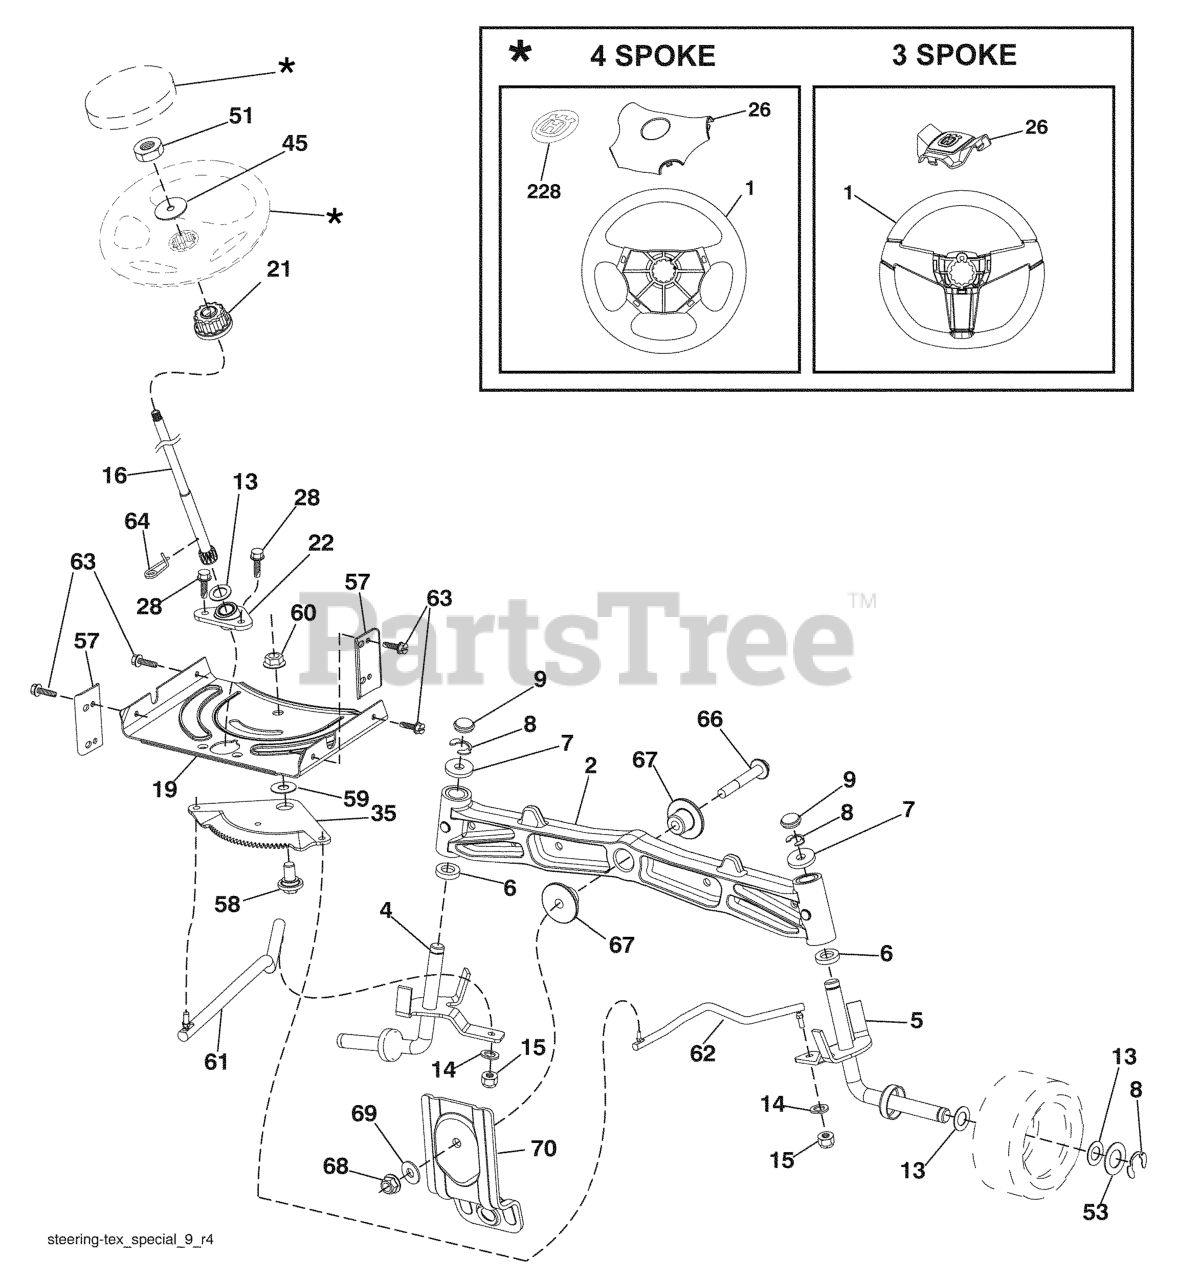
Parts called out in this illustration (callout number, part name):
1	RP INSERT.CAP.WHL.STRG.HUSQ.
2	AXLE.CAST.IRON
4	SPINDLE.WELDED.LH.15"TEX
5	SPINDLE.WELDED.RH.15"T
6	THRUST WASHER
9	CAP.SPINDLE.BLACK
14	WASHER, LOCK 3/8
15	NUT CROWNLOCK 3/8-24
16	SHAFT, STEERING
19	PLATE.STEER.DDL.NLT/NG
21	ADAPTER, WHEEL STNG..
22	BUSHING.ASM.STEERING.A
26	RP INSERT.CAP.WHL.STRG.HUSQ.
28	SCREW, 3/8-16X3/4
35	GEAR.SECTOR.PLATE.DDL.
45	WASHER 9/16"ID, 2 3/8"OD
51	NUT.HEX.1/2-20
53	WASHER.HARDENED
57	BRACKET.UPSTOP.TEX
58	BOLT.SHOULDER.SECTOR.P
59	WASHER.THURST.SECTOR.S
60	NUT FLANGE LOCK 5/8-11
61	DRAGLINK.LH.BALLSTUD.D
62	DRAGLINK.RH.BALLSTUD.D
63	SCREW
64	RETAINER.CLIP.SPRING.S
66	BOLT HEX FGHD 7/16-14 X 3 SERR
67	BUSHING.PM.FRONT AXLE
68	NUT.LOCK.FLANGE.7/16
69	WASHER.1.5X.505X.118
70	BRKT.DECK.SUSPENSION.F
228	DECAL.WHEEL.STRG.LGN.H
